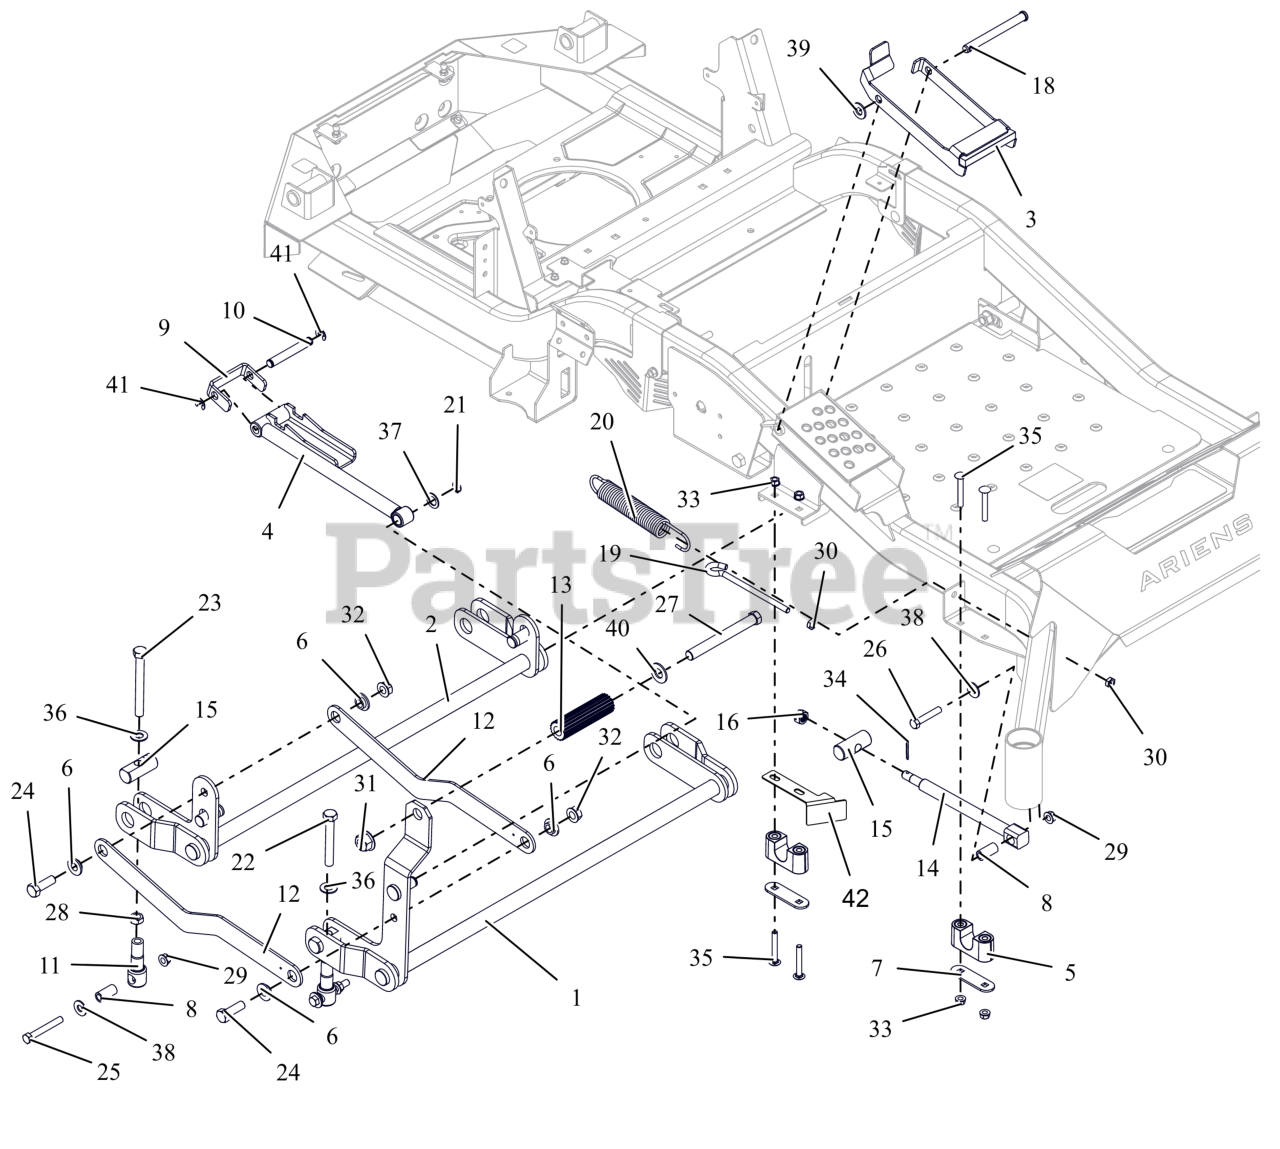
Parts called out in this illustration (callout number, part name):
1	WLDMT, FRONT DECK LIFT PIVOT
2	WLDMT, REAR DECK LIFT PIVOT
3	BRKT, HOC TRANSFER LOCK
4	WLDMT, HOC ARM
5	ASM-BUSHING, DECK LIFT
6	BSHG-FLG .515X.750X.395X1.120
7	PLATE, BEARING SUPPORT
8	SPACER, DECK LEVELING
9	BRKT, HOC LINE
10	ROD, HOC PIVOT
11	LINK, DECK LIFT FORMED
12	LINK, DECK LIFT
13	ROD, FOOT PEDAL (BLACK)
14	DRAG,LINK-HD
15	PIN, DECK LIFT
16	NUT-SL .50-13
18	PIN-SLIC .50X4.97X4.55 -ZCC
19	BOLT,.38-16 X 5.25-.62 DIA EYE
20	SG-TENS .162X1.25X8.25 WLD 25
21	RG-RTNG-EXT .625X.050
22	BLT, HEX .50-13X3.50F G5 ZCC
23	BLT, HEX .50-13X4.50F G8 ZCC
24	BLT,HEX .50-13X1.50 G5 ZCC
25	BLT, HEX .38-16X2.75 G8 ZCC
26	BLT,HEX .38-16X2.00 G5 ZCC
27	BLT, HEX .62-11X5.50 G5 FBP
28	NUT-JAM .500-13 G2 ZCC
29	NUT-LK-TOP-FLG .38-16 ZC120
30	NUT-JAM .375-16 G2 ZCC
31	NUT,FLG-TOP LK .625-11 FBP
32	NUT-LK-TOP-FLG .500-13 GF ZCC
33	NUT,LK-CTR-FLG .31-18 GF ZCC
34	PIN,CTR.12X1.25EXTPRSQCT ZC120
35	BLT, RHSSN.31-18X2.25 G5 ZCC
36	WSHR, FLT .557X1.040X.102 ZCC
37	WSHR, FLT .630X1.005X.062 ZCC
38	WSHR,FLT .438X1.00X.083 ZCC
39	WSHR,FLT .531X1.062X.095 ZCC
40	WSHRFLT 5/8SAE CARBHARD FBP
41	RG-RTNG-EXT .500X.042 (E)
42	GUARD, STOP CE 60 (BLACK)
